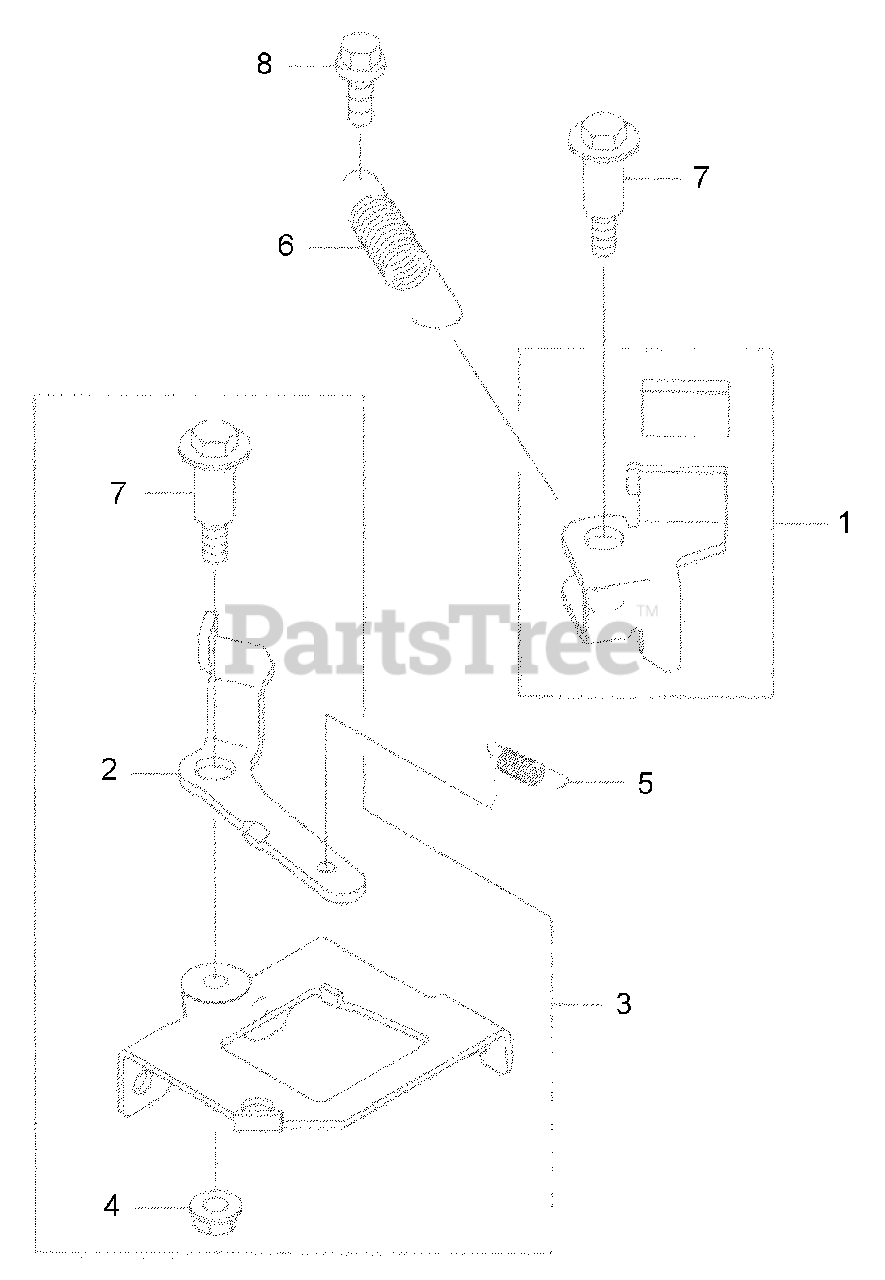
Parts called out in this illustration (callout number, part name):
1	Lever
2	Arm
3	Brake Panel Assy.
4	Nut
5	Spring
8	Flanged Bolt
